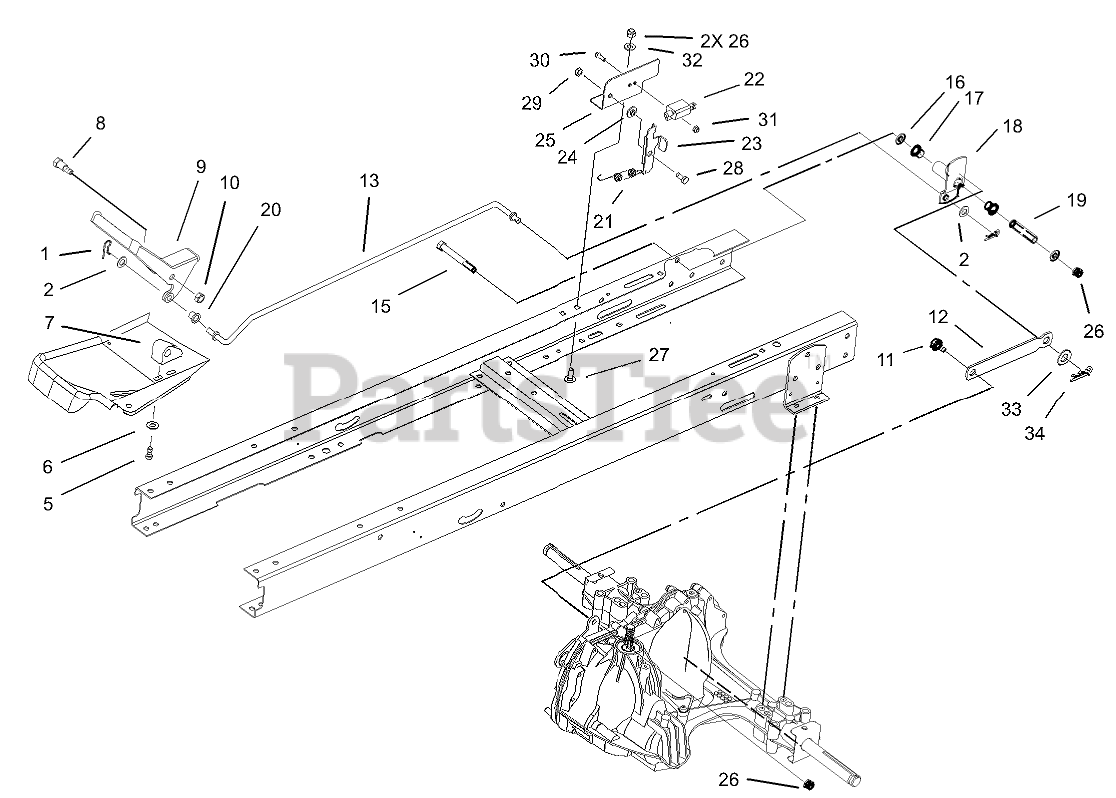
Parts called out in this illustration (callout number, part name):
1	PIN-COTTER
2	WASHER-FLAT
5	SCREW-PLASTITE
6	WASHER-FLAT
7	BLOCK-PIVOT
8	SCREW-SHOULDER, HH
9	PEDAL-CONTROL, SPEED
10	NUT-LOCK, NI
11	BOLT-SHOULDER
12	LINK-CONTROL, SPEED
13	ROD-CONTROL, SPEED
15	SCREW-HH
16	WASHER-FLAT
17	BUSHING-NYLINER
18	PIVOT ASM
19	SPACER-PIVOT
20	BUSHING-FLANGED
21	SPRING-EXTENSION
22	SWITCH-POLE, SINGLE
23	BRACKET-PIVOT
24	WASHER-STEPPED
25	BRACKET-ADJUSTMENT
26	NUT-LOCK, NI
27	SCREW-CARR
28	SCREW-HHF
29	NUT-LOCK, NI
30	SCREW-SHH
31	NUT-LOCK
32	WASHER-PLAIN
33	WASHER-FLAT
34	PIN-HAIR
